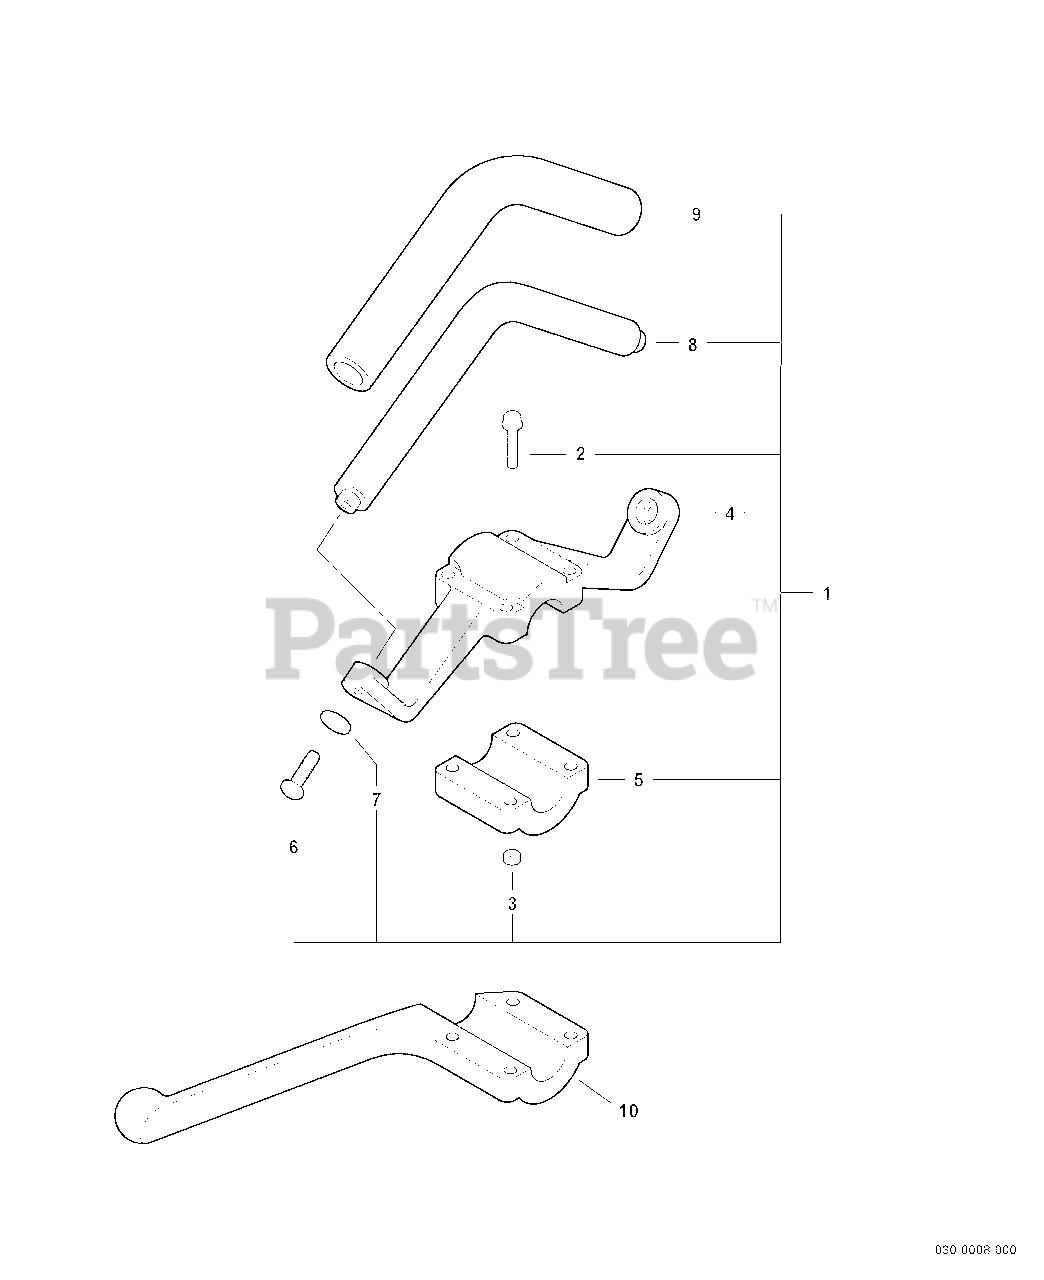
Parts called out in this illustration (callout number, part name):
1	HANDLE ASSY, FRONT
2	SCREW 5×35
3	NUT M5
4	BRACKET, HANDLE
5	BRACKET, HANDLE - LOWER
6	SCREW, TAPPING 5×20
7	WASHER, FLAT 5.5×10×0.8
8	HANDLE, SUPPORT
9	GRIP, HANDLE
10	BAR, BARRIER
